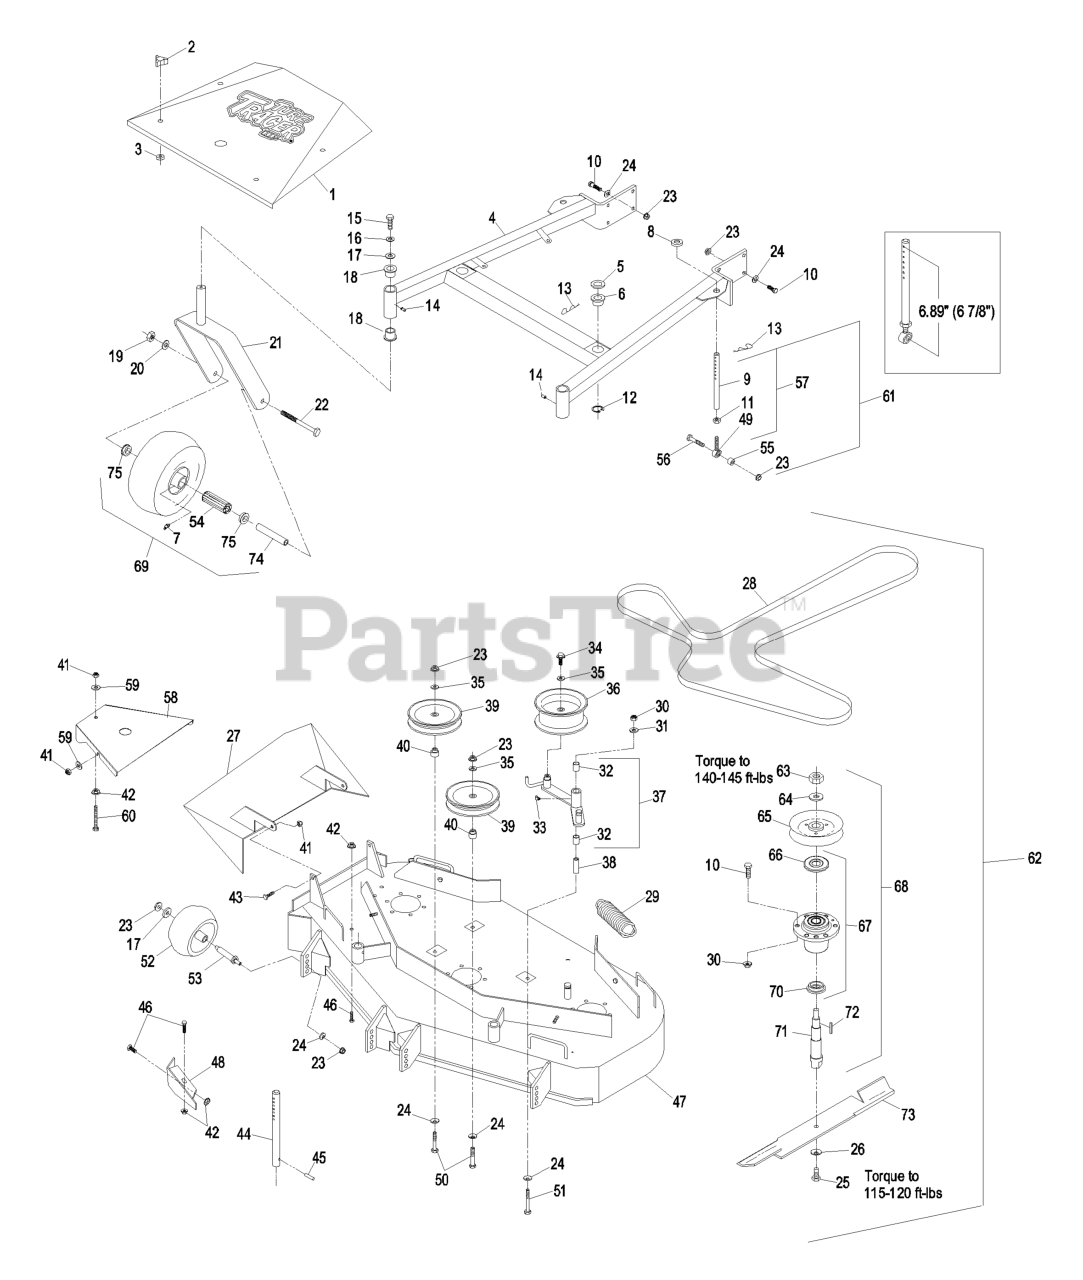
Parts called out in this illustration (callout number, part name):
2	KNOB-3 PRONG
4	DECK SUPPORT W/BSHGS 48"
5	SPACER-DECK SUPPORT
6	BUSHING-DECK
7	FITTING-GREASE
9	LINK,SUPPORT
10	SCREW-HH
11	NUT-HEX
12	RING-RETAINING
13	PIN,HAIR COTTER
14	FITTING-GREASE
15	SCREW-HH
16	WASHER-LOCK
18	BEARING-FLANGED
19	NUT-HH
20	WASHER-LOCK
22	SCREW-HH
23	NUT-HHF, WHIZ
24	WASHER-BELLEVILLE
25	SCREW-CAP
26	WASHER-SPRING
27	WLD,DISCHARGE CHUTE 36/48
28	BELT - V, B
30	NUT-LOCK, NI
31	WASHER-FLAT
32	SLEEVE-BEARING
33	FITTING-GREASE, 90 DEG
34	SCREW-HHF
35	WASHER-FLAT
37	Wld, Arm (1-412394-03) W/Bushings
38	BUSHING-PIVOT, IDLER
39	PULLEY-IDLER
40	BUSHING-IDLER
41	NUT-LOCK, NI
43	SCREW-HH
44	ROD,DECK SUPPORT
46	SCREW-HH
47	ASM,DECK W/DECALS TTHP/MH
49	BALLJOINT
50	SCREW-HH
51	SCREW-HH
52	ROLLER-SCALP, ANTI
54	BEARING
56	SCREW-HH
58	SHIELD,BELT
59	WASHER-FLAT
60	BOLT,TAP HH
62	Asm, Deck Complete
65	SHEAVE,W/HUB 5.72
66	GUARD-BEARING, TOP
69	KIT, SP CASTER WHEEL REPL
70	SPACER-GUARD, BOTTOM
71	SPINDLE,SHAFT
72	KEY-RECTANGLE
74	SPACER FRONT CASTER
75	BUSHING, SP CASTER
